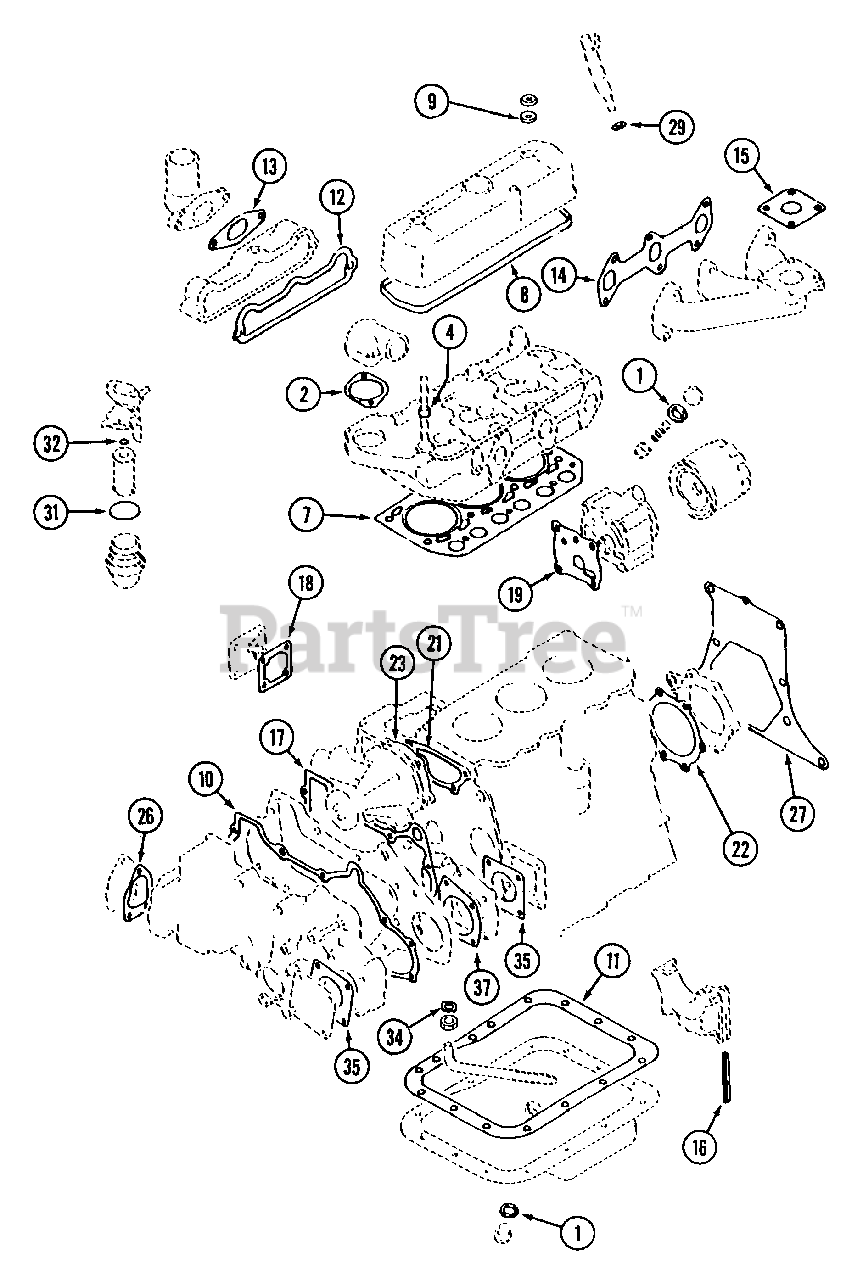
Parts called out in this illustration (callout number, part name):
1	Gasket, Drain Plug
2	Gasket
4	Seal, Valve
7	Gasket, Cylinder
8	Gasket, Rocker Cover
10	Gasket, Gear Case
11	Gasket, Oil Pan
12	Gasket, Intake Manifold
13	Gasket, Inlet Pipe
14	Gasket, Exhaust Manifold
17	Gasket, Front Plate
18	Gasket, Cover
19	Gasket, Oil Pump
21	Gasket, Water
22	Gasket, Oil Seal
23	Gasket, Water Pump
26	Gasket Governor Cover
27	Gasket Rear Plate
29	Gasket, Nozzle Holder
31	O-Ring, Filter Cup
32	O-Ring
34	Washer, Seal
35	Gasket, Oil Pump Cover
37	Gasket, Housing
